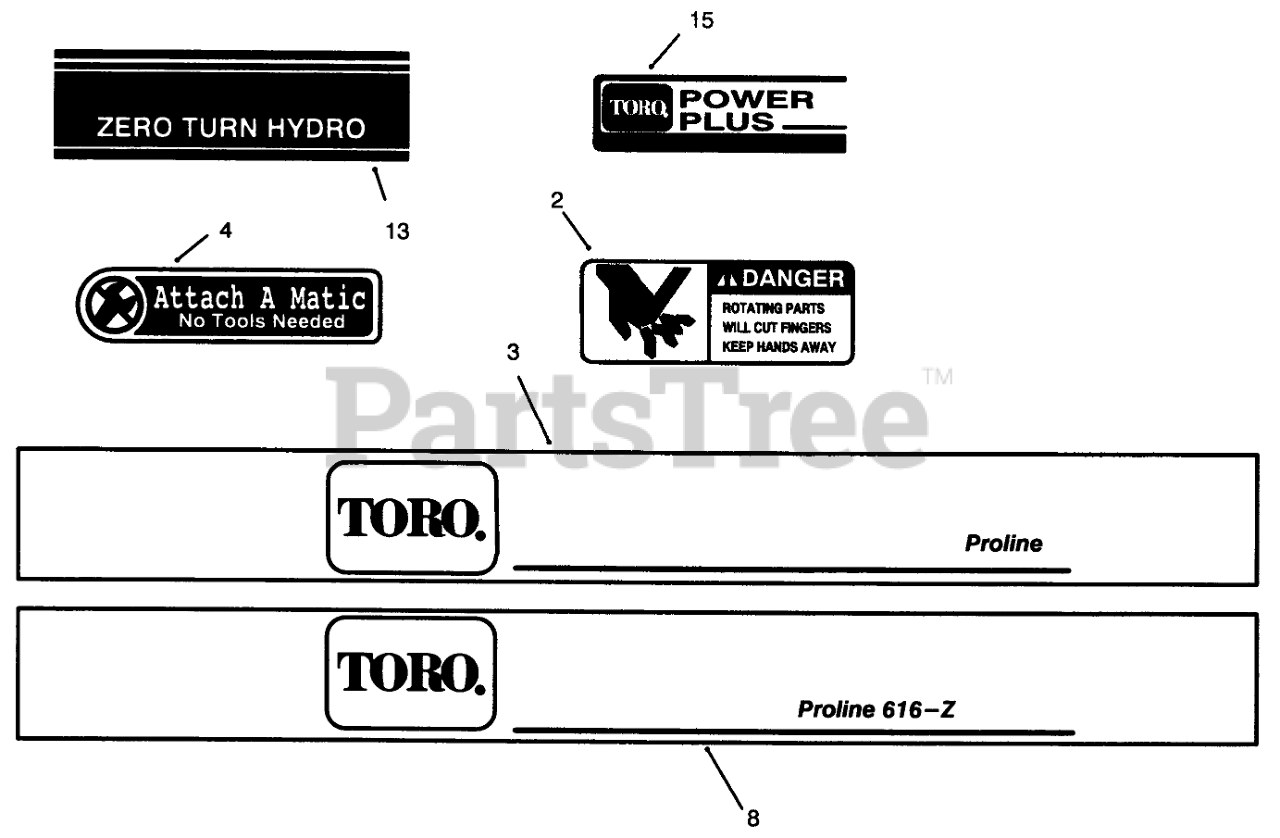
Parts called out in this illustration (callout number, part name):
2	DECAL - DANGER
3	DECAL-TORO REAR
4	Decal-Attac-O-Matic
8	DECAL - TORO 616-Z
13	DECAL-ZERO TURN HYD
15	DECAL POWER PLUS 16
